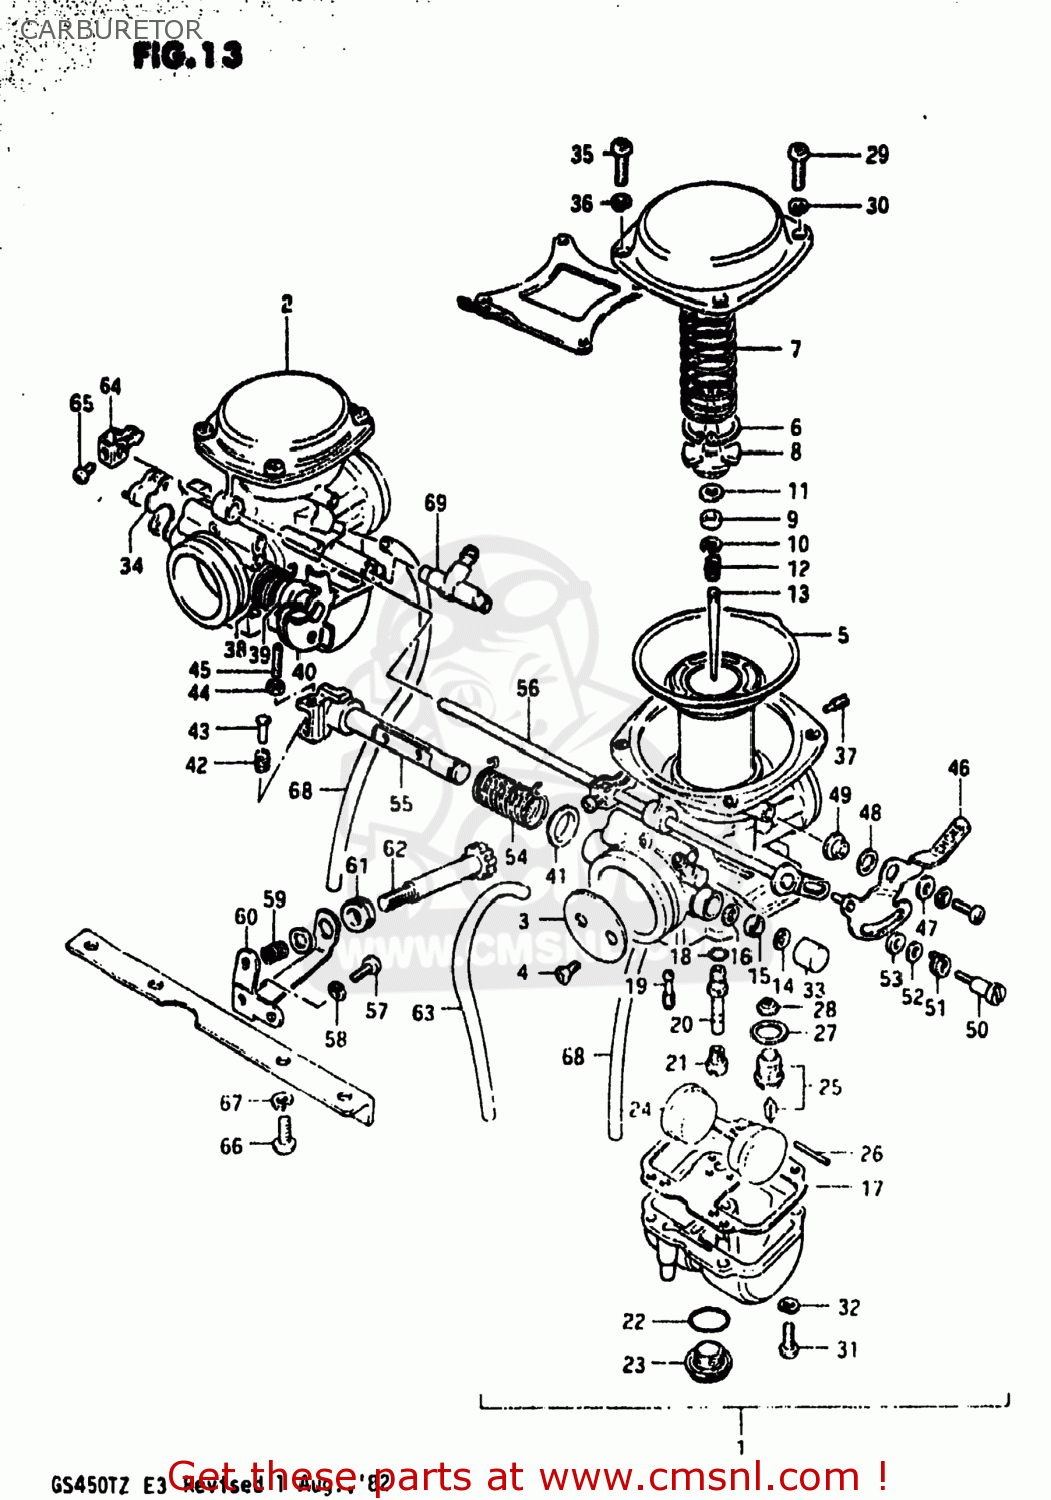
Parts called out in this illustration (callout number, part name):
1	CARBURETOR ASSEMBLY
2	CARBURETOR ASSEMBLY
3	VALVE,THROTTLE
4	SCREW
5	DIAPHRAGM
6	E RING
7	SPRING,DIAPHRAGM
8	HOLDER,GUIDE
9	RING
10	CLIP
11	WASHER
12	SPRING
13	NEEDLE JET
14	E RING
15	GASKET,THROTTLE SHAFT (NAS)
16	SEAL
17	GASKET,FLOAT CHAMBER (NAS)
18	O-RING
19	JET,PILOT
20	JET,NEEDLE
21	JET,MAIN(115)
22	O-RING
23	SCREW,GUIDE
24	FLOAT
25	VALVE ASSY,NEEDLE
26	PIN,FLOAT
27	GASKET,MAIN JET HOLDER (NAS)
28	FILTER
29	SCREW
30	LOCK WASHER
31	SCREW
32	LOCK WASHER
33	CAP
34	GASKET
35	SCREW
36	LOCK WASHER
37	JET,AIR(1.6)
38	SPRING
39	RING
40	SHAFT ASSEMBLY
41	RING
42	SPRING,THROTTLE SCREW
43	PIN,THROTTLE LEVER
44	NUT
45	SCREW
46	LEVER,STARTER
47	WASHER,STARTER LEVER (4.1X12X0.8)
48	WASHER,STARTER LEVER
49	RING,STARTER LEVER
50	SCREW
51	SPRING,STARTER LEVER S
52	WASHER
53	WASHER
54	SPRING
55	SHAFT ASSEMBLY
56	SHAFT,STARTER
57	SCREW
58	LOCK WASHER
59	SPRING
60	BRACKET,THROTTLE ADJUST
61	BUSHING,THROTTLE ADJUSTER
62	SCREW
63	HOSE 4.5X8X390
64	ARM, STARTER
65	SCREW
66	SCREW 6X12
67	LOCK WASHER
68	HOSE
69	NIPPLE
